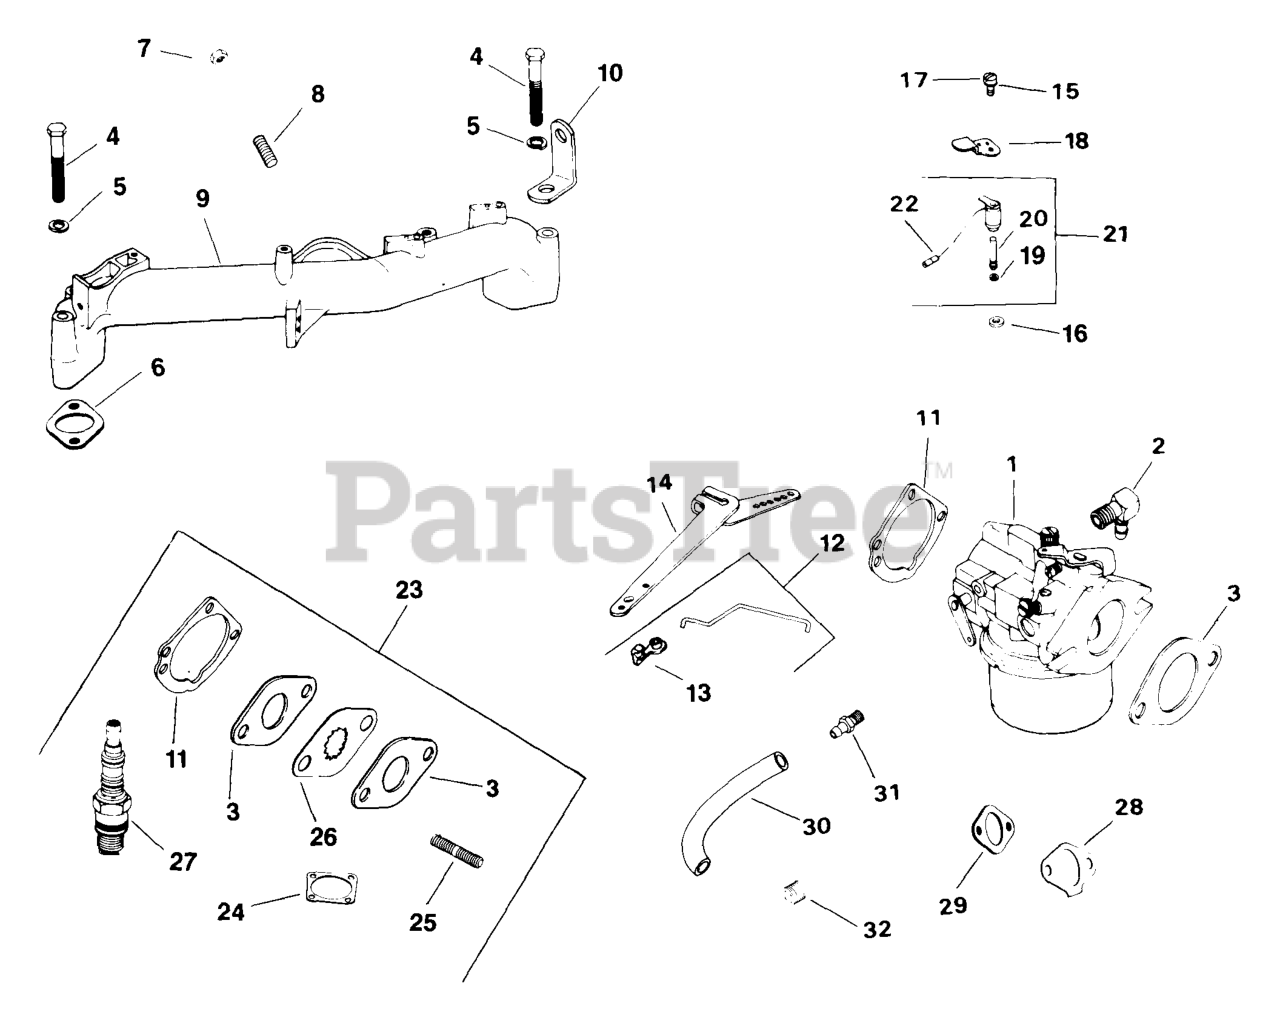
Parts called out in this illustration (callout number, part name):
1	KIT, CARBURETOR W/LINKAGE - DISCONTINUED
2	CONNECTOR, 90 DEG. HOSE
3	GASKET, CARBURETOR
4	SCREW, CAP HD 5/16-18x2 3/4" - DISC.
5	WASHER, SPRING LOCK 5/16"
7	NUT, 5/16-18 GRADE 2 USE 25 100 21-S
8	STUD, 5/16-18X1" USE 25 072 06-S
9	MANIFOLD - (#DSC)
10	STRAP - DISCONTINUED
11	GASKET, AIR CLEANER ELBOW
12	KIT, GOVERNOR LINKAGE - DISCONTINUED
13	BUSHING - USE 25 158 11
14	ARM, GOVERNOR - DISCONTINUED
2575505-S	KIT, SOLENOID
2575702-S	KIT, CARBURETOR REPAIR
5205364-S	CARBURETOR - (#DSC)
